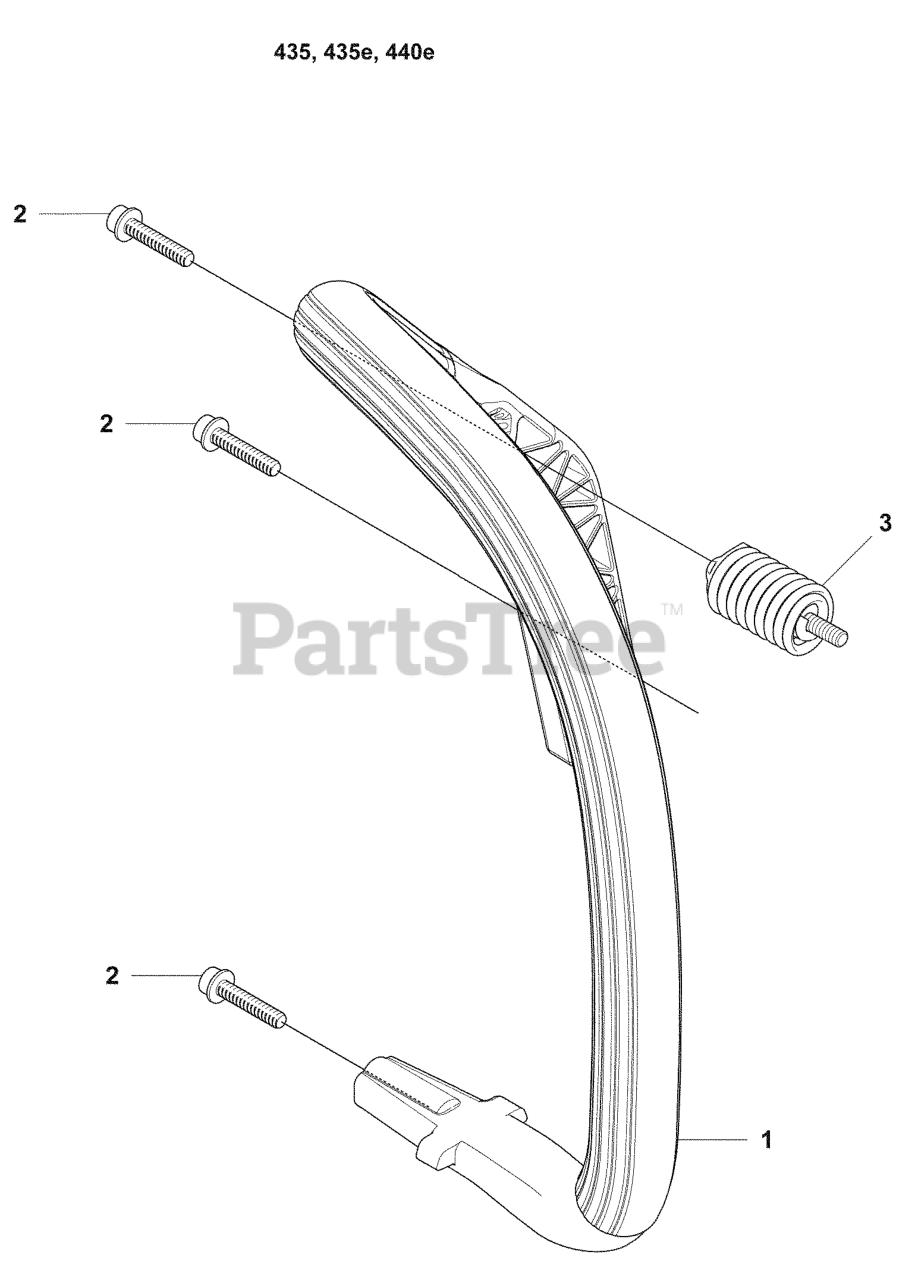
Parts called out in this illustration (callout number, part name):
1	FRONT HANDLE
2	SCREW
3	INSULATOR
